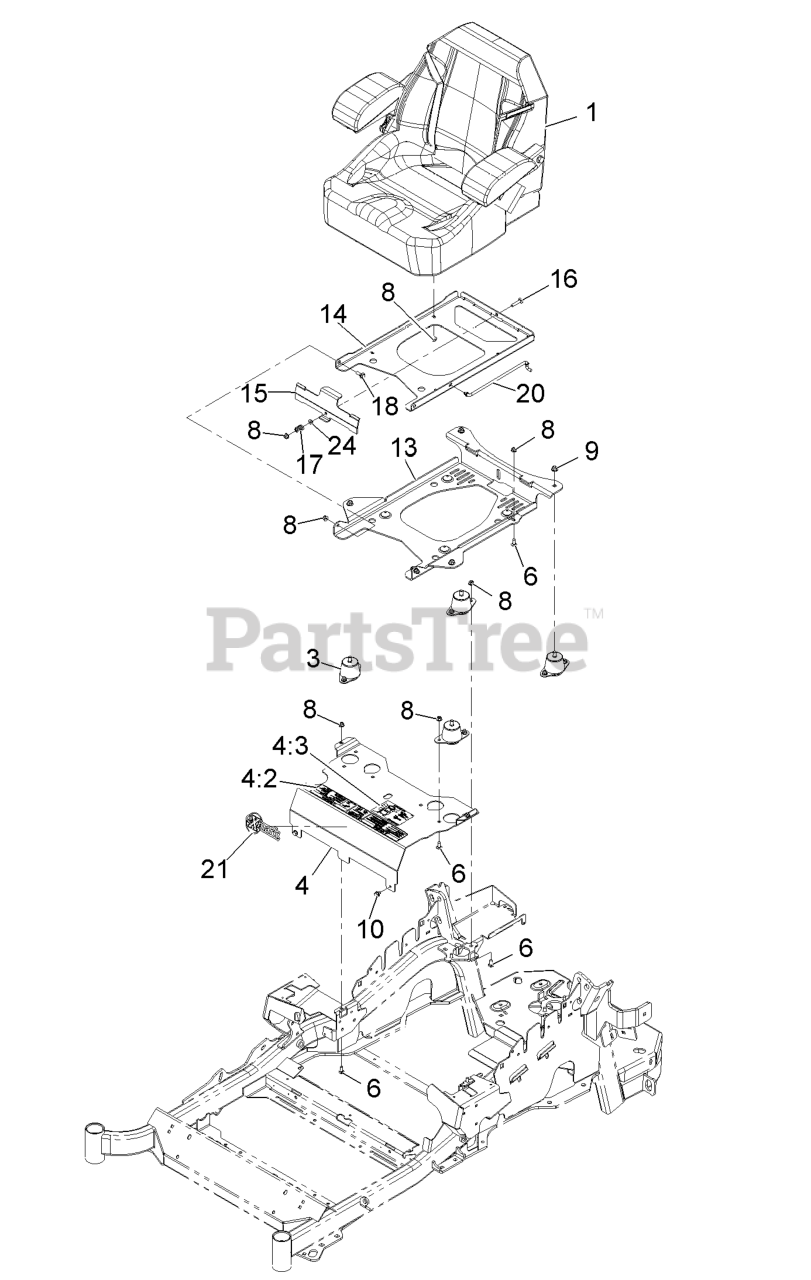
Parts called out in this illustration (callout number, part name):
3	ISOLATOR-SEAT
4	MOUNT-SEAT
4:2	DECAL-CONSOLE
4:3	DECAL-SERVICE AID
6	SCREW-CARR
8	NUT-HF, NI
9	NUT-HF, NI
13	PLATE-SUPPORT, SEAT TILT
14	PLATE-FRAME, SEAT TILT
15	PLATE-LATCH, SEAT
16	BOLT-CARR
17	SPRING-COMPRESSION
18	SCREW-SHOULDER
20	ROD-PROP
24	WASHER-PLAIN
